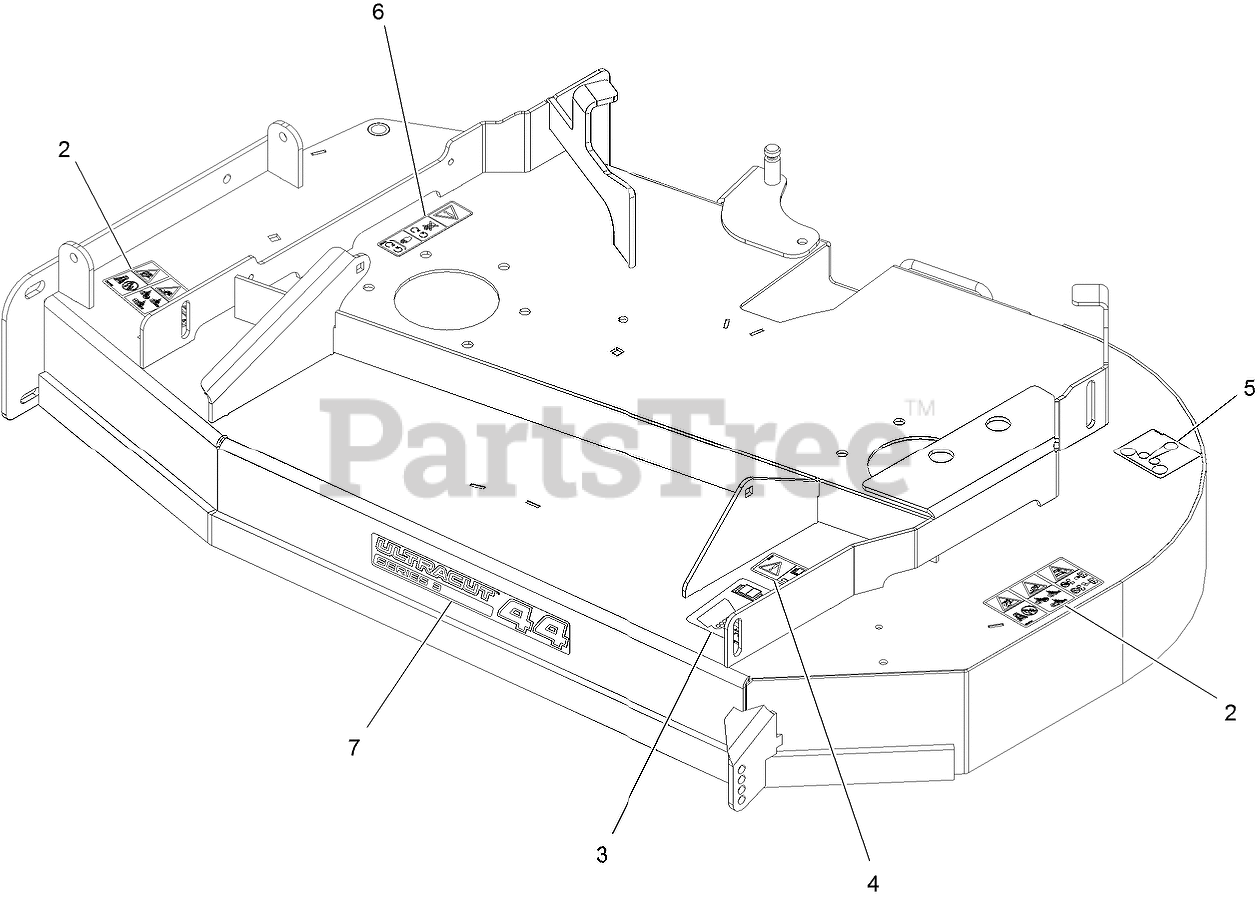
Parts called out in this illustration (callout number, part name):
2	DECAL-DANGER THROWN OBJECTS
3	DECAL-ROLLER, ANTI-SCALP
4	DECAL-BOLT TORQUE
5	DECAL-ROUTING, BELT
6	DECAL-COVER, MISSING
7	Decal-Ultracut 44 Series 3
